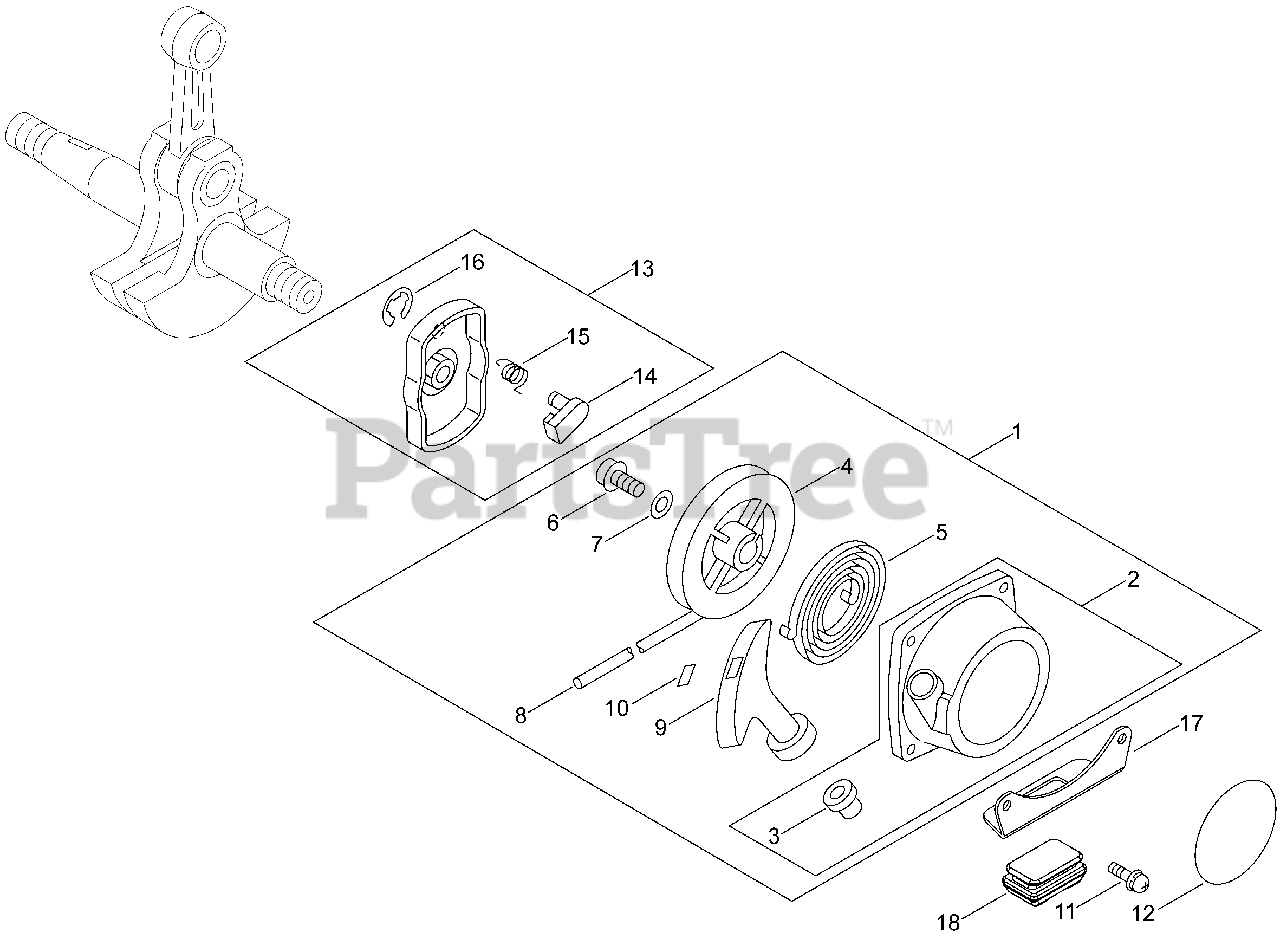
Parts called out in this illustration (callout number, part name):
1	STARTER ASSY, RECOIL
2	CASE, STARTER
3	GUIDE, ROPE
4	REEL, ROPE
5	SPRING, RECOIL
8	ROPE, STARTER 3.8×1400
9	GRIP, STARTER
10	RETAINER, ROPE
11	SCREW 4×18
12	LABEL, ECHO
13	PAWL ASSY, STARTER
14	PAWL, STARTER
15	SPRING, RETURN
16	E-RING 4
17	PLATE, ANGLE
